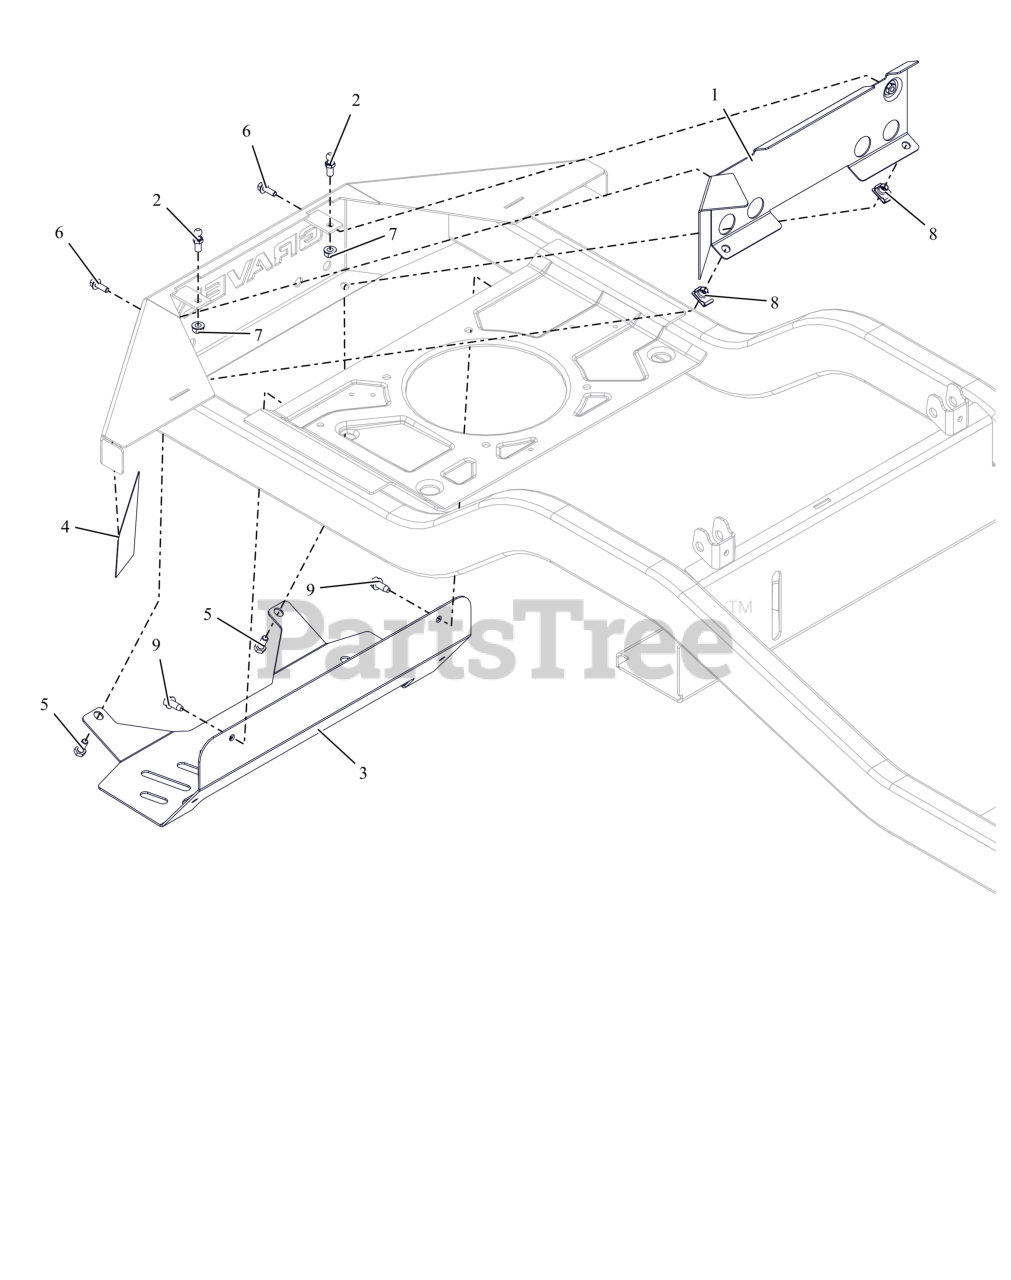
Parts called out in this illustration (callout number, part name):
1	WMT, HEAT BAFFLE
2	STUD- BALL
3	SHIELD, HEAT (HD)
4	TAPE, HEAT DEFLECTOR
5	BLT,HEX .31-18X.75 G5 ZCC
6	BLT,HEX-FLG .25-20X.75 G5 BFP
7	NUT,LK-CTR-FLG .31-18 GF ZCC
8	NUT-CLIP RETAINER 5/16-18X.56
9	SCR,TAP .312-18X.75 HWH TR ZCC
